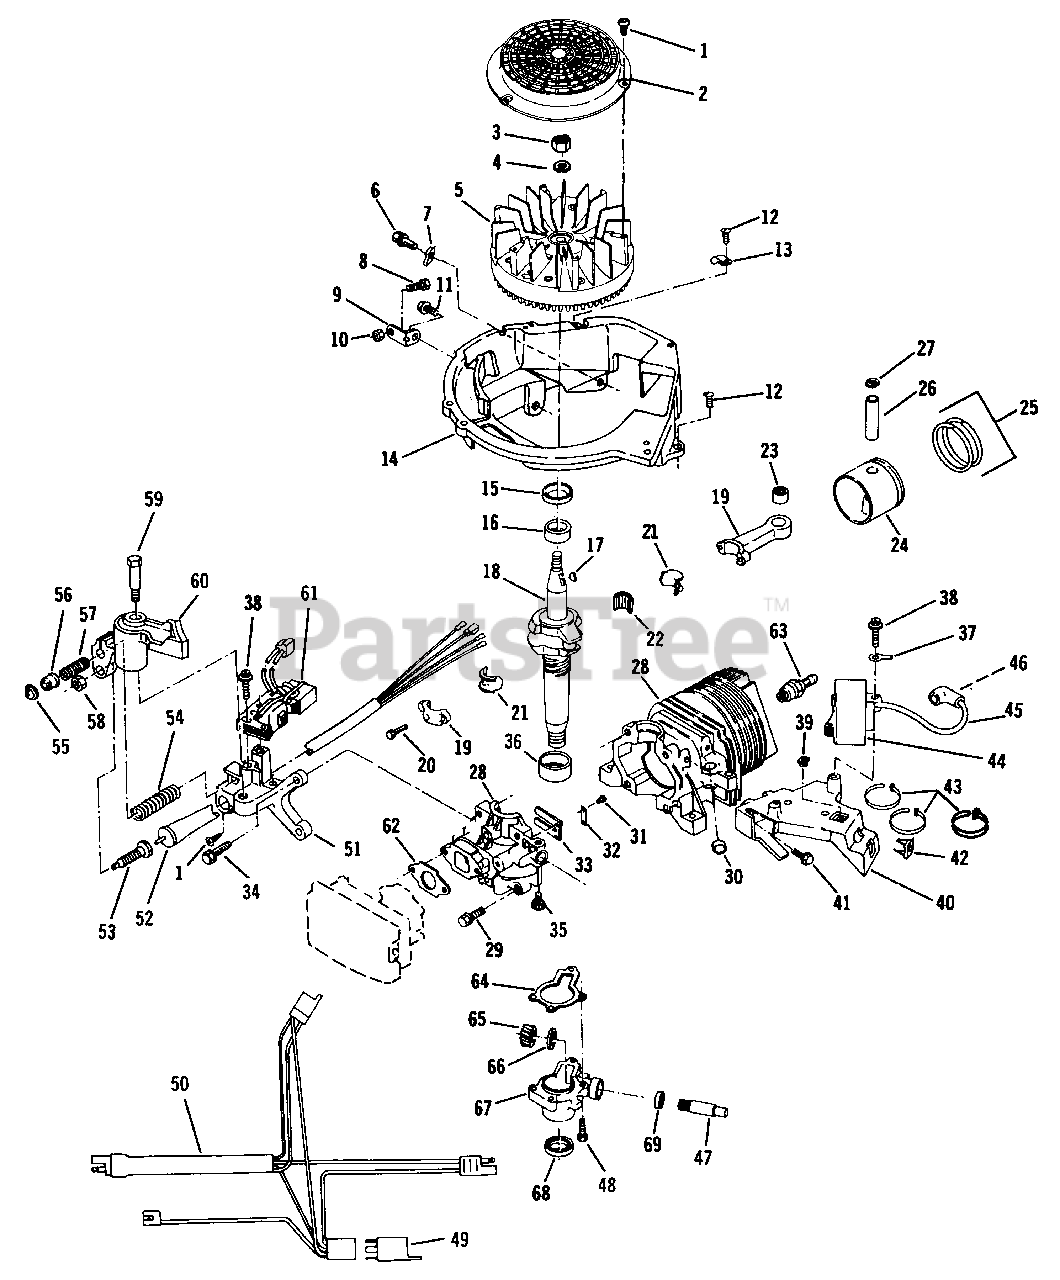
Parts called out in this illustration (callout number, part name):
1	Screw-Flywheel Screen and Switch
2	Screen-Flywheel
3	Nut-Flywheel
4	Lockwasher
5	Flywheel
6	Screw
7	"J" Clip
8	Bolt-Brace-Alt. Brk't.
9	Brace-Alt. Bracket
10	Locknut-Brace-Alt. Brk't.
11	Screw
12	Screw-Shd. Base to C.D. Brk't. and Clamp to Shd.B.
13	Tie Rap
14	Base-Shroud
15	Oil Seal-Upper
16	Bearing-Upper
17	Key-Flywheel
18	Crankshaft
19	Connecting Rod Assembly.
20	Screw-Cap
21	Liner Split
22	Needle Bearing Set
23	Bearing Assembly
24	Piston and Ring Set
25	Ring Set
26	Wrist Pin
27	Retaining Ring
28	Cylinder and Crankcase Cover Assembly
29	Screw-Cover to Crankcase
30	Plug
31	Screw-Reed to C'case Cover
32	Plate-Reed Hold Down
33	Reed
34	Screw-Alt. and Brake Mtg. Brk't
35	Set Screw-Starter Assembly
36	Bearing-Lower
37	Terminal-Ground Lead
38	Screw-C.D. and Alt. Mtg.
38	Screw-C.D. Mtg.
39	Grommet-C.D. Bracket
40	Bracket-Ignition Mtg.
41	Screw
42	Grommet-C.D. Brk't.
43	Tie Strap
44	C.D. Ignition Module and Lead Assembly
45	High Tension Lead and Cover Assembly
46	Spring Terminal
47	Driveshaft
48	Screw-Gear Box
49	Relay
50	Wire Harness Assembly
51	Bracket-Alt. and Brake
51	Bracket-Brake
52	Brake Switch Assembly
53	Plunger
54	Spring-Brake
55	Retainer
56	Actuator-Brake Lever
57	Spring-Cable Retainer
58	Nut
59	Bolt-Shoulder
60	Brake Assembly
61	Alternator Assembly
62	Gasket-Carb. to Crankcase Cov.
63	Spark Plug
64	Gasket-Gear Box
65	Gear
66	Washer-Thrust
67	Gear Box Assembly
68	Oil Seal Crankshaft
69	Seal-Driveshaft
